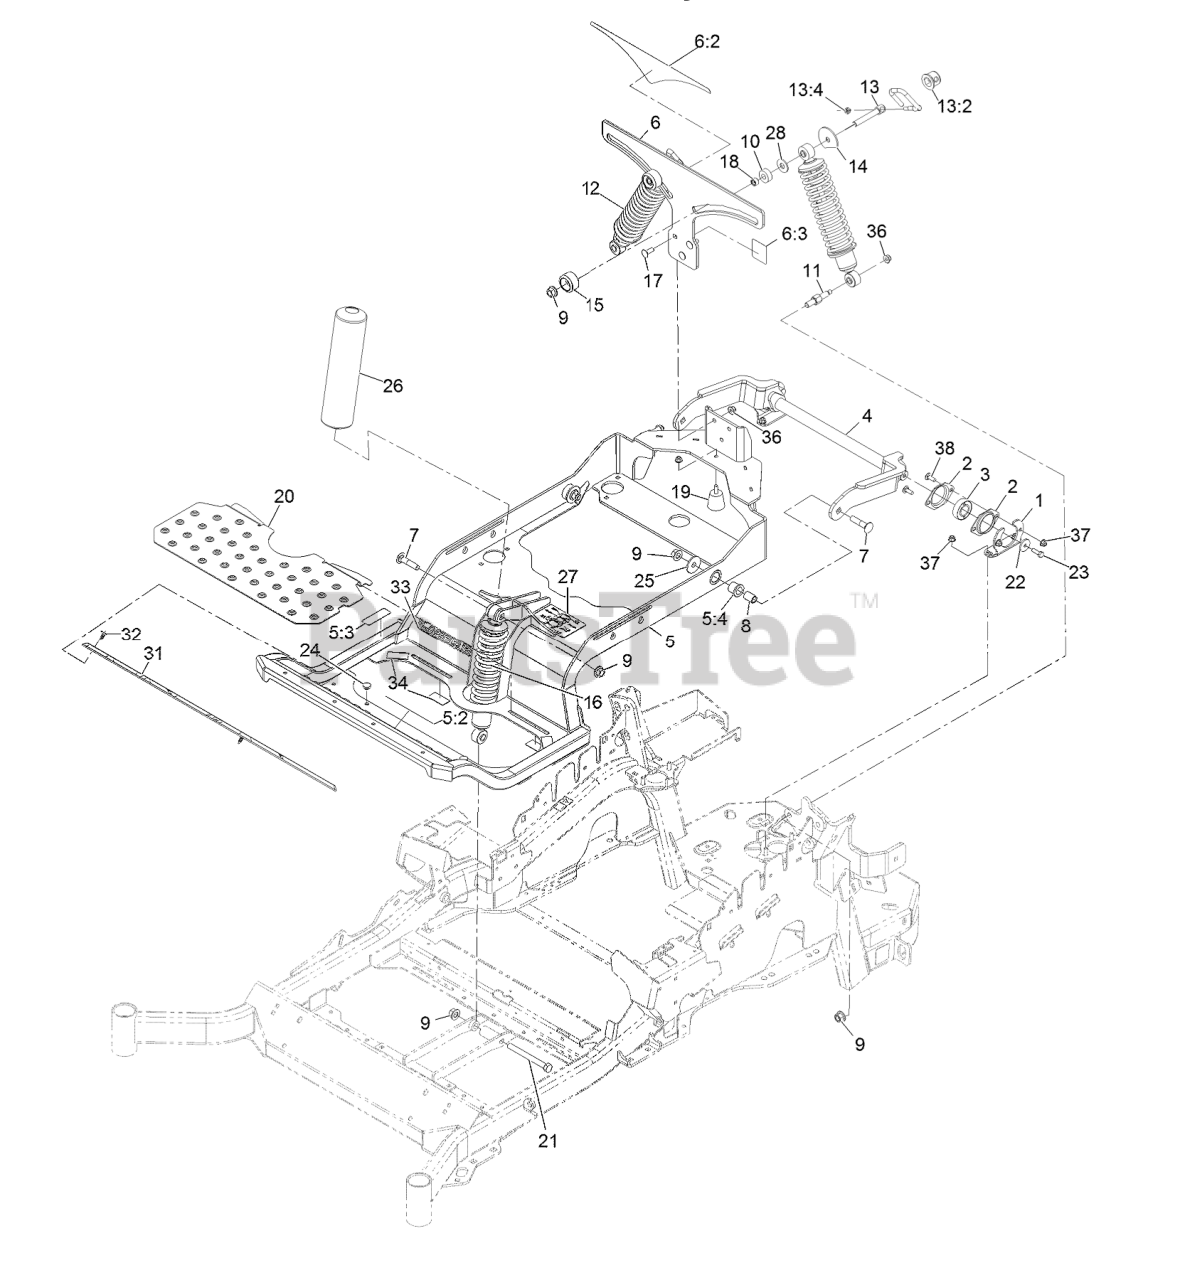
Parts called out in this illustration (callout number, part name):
1	PLATE-MOUNT, SHOCK
2	MOUNT-LOWER
3	BRACKET-BEARING
4	HOUSING-BEARING, FLANGE
5	BEARING
6	ARM-TRAILING
7	SUBFRAME ASM
7:2	DECAL-DANGER
7:3	DECAL-BRAKE, PARKING
7:4	BUSHING-FLANGE
8	BRACKET-MOUNTING
8:2	DECAL-ADJUSTMENT, RIDE
8:3	DECAL-LOCK, CAM
9	SCREW-CARR
11	SPACER-ALUMINUM
12	Nut-Lock 1/2-13
14	BOLT-SHOULDER
15	SHOCK/SPRING ASM
16	CAM LOCK ASM
16:2	CAP-LOCK
16:4	NUT-HEX
17	PLATE-STOP
18	KNOB-FRONT
22	SHOCK/SPRING ASM
24	ISOLATOR-SEAT
25	BOLT-CARR
26	NUT-HF, NI
27	PLATE-SUPPORT, ISO SEAT
28	NUT-HF, NI
29	PLATE-FRAME, SEAT
30	SCREW-SHOULDER
31	SEAT-EXMARK STANDARD
32	ROD-PROP
33	LH PLATE ASM (W/STUDS)
34	SCREW-CARR
35	SCREW-HH
36	BEARING-NEEDLE
37	BUMPER-RUBBER
39	SCREW-CARR
40	PLATE-LATCH,SEAT
41	WASHER-PLAIN
42	SPRING-COMPRESSION
43	BOLT-CARR
51	SCREW-HH
57	WASHER-FLAT
58	SCREW-HH, THREAD LOCKING
60	WASHER-THRUST
61	COVER-HOSE
62	TIE-CABLE
65	COVER-SHOCK
66	DECAL-SERVICE AID
67	WASHER-FLAT
71	RH PLATE ASM (W/STUDS)
72	Bolt-Carriage 5/16-18 X 1 1/4
